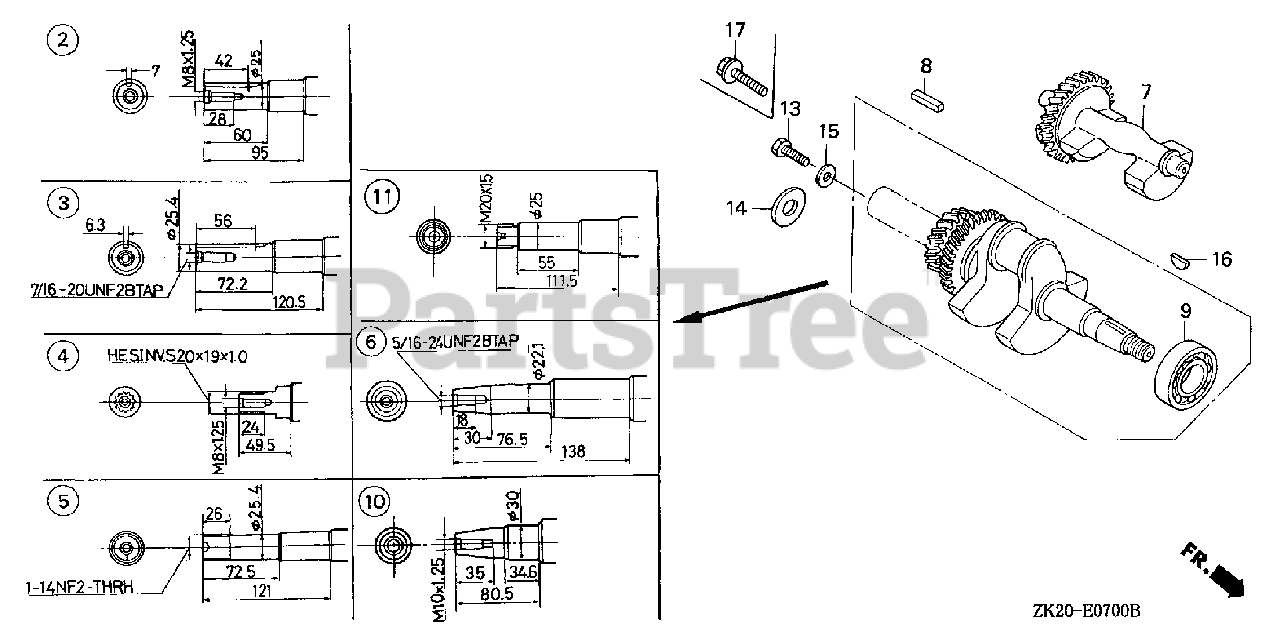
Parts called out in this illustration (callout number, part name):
3	CRANKSHAFT (Q-TYPE)
8	KEY (6.3X6.3X43)
9	BEARING, RADIAL BALL (6206)
